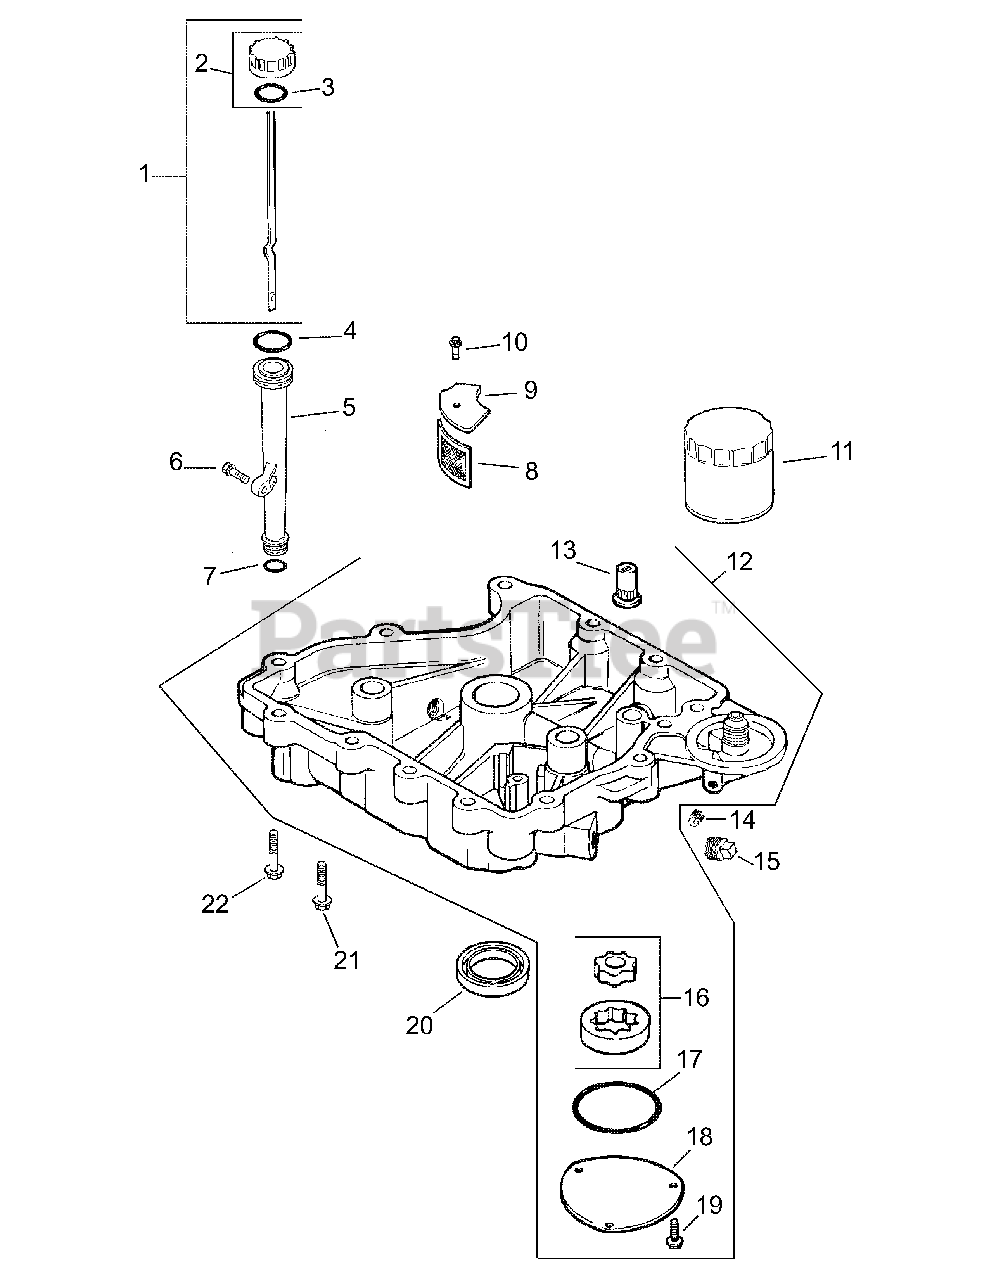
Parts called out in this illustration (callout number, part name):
1	Dipstick (Includes 2, 3)
2	Kit, Oil Fill Cap (Includes 3)
3	O-ring
4	O-ring, Upper Oil Fill Tube
5	Tube, Oil Fill
6	Screw, Hex. Flange M6 x 1.0 x 25
7	O-ring, Lower Oil Fill Tube
8	Screen, Oil Pickup
9	Cover, Oil Pickup Screen
10	Screw, Hex. Flange M5 x 0.8 x 16
11	Filter, Oil
12	Pan, Oil (Includes 13, 16-19)
13	Valve, Oil Pressure Relief
14	Plug, Sq. Hd. 1/8"
15	Plug, Sq. Hd. Solid 3/8"
16	Pump Assembly, Oil
17	O-ring, Oil Pump Cover
18	Cover, Oil Pump
19	Screw, Hex. Flange M5 x 0.8 x 16
20	Seal, Oil (P.T.O. End)
21	Screw, Hex. Flange M8 x 1.25 x 45
22	Screw, Hex. Flange M8 x 1.25 x 45
